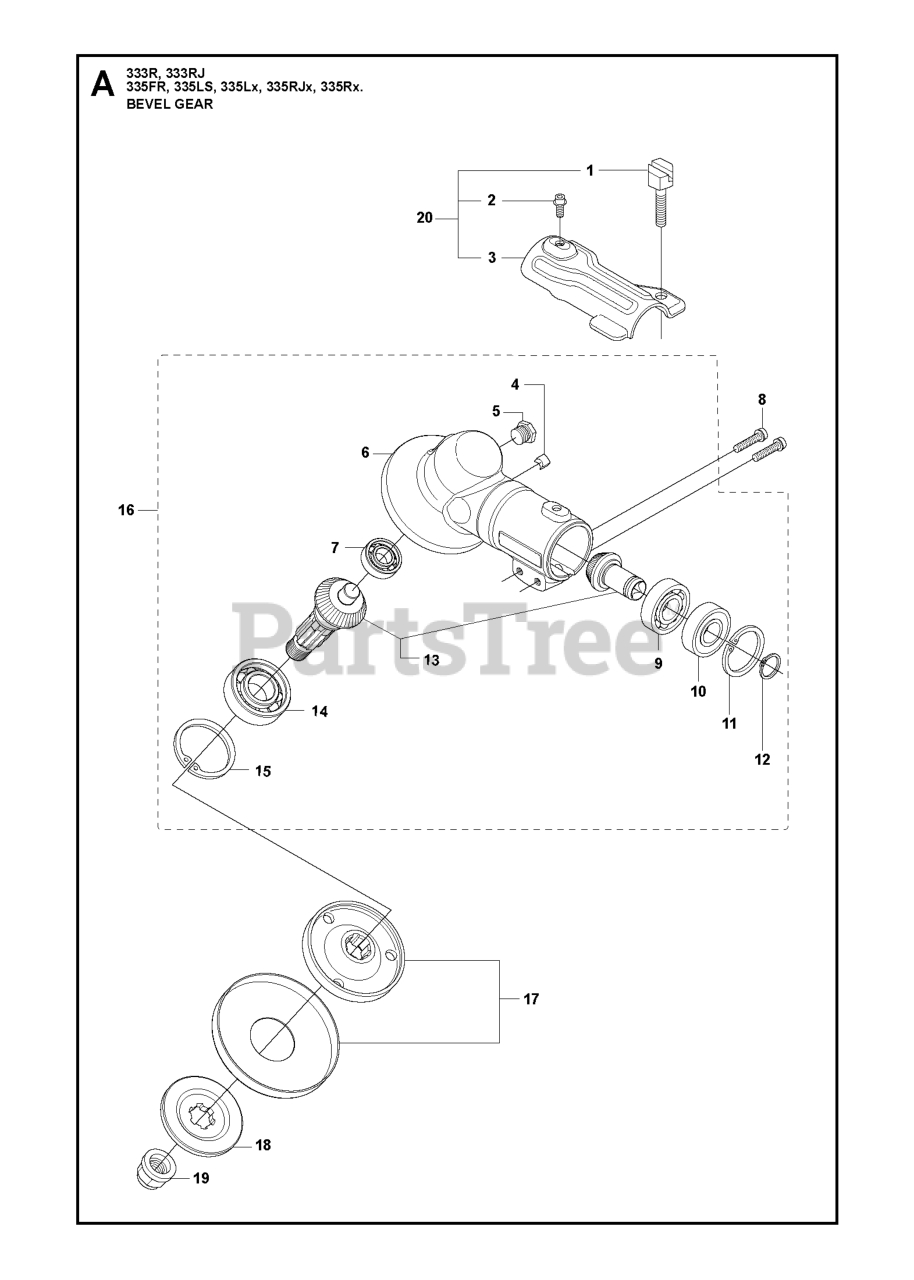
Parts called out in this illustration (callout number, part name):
2	SCREW
3	RP HOLDER
7	BALL BEARING 24X9X1/609ZR
9	BALL BEARING
10	BALL BEARING
11	RETAINING RING SGH 28
12	SEEGER CLIP
13	SPARE PARTS KIT
14	BALL BEARING
15	RETAINING RING
16	%GEAR CASE ASSY
16	GEAR COMPLETE
17	RP CARRIER
18	RP FLANGE
20	CLAMP
